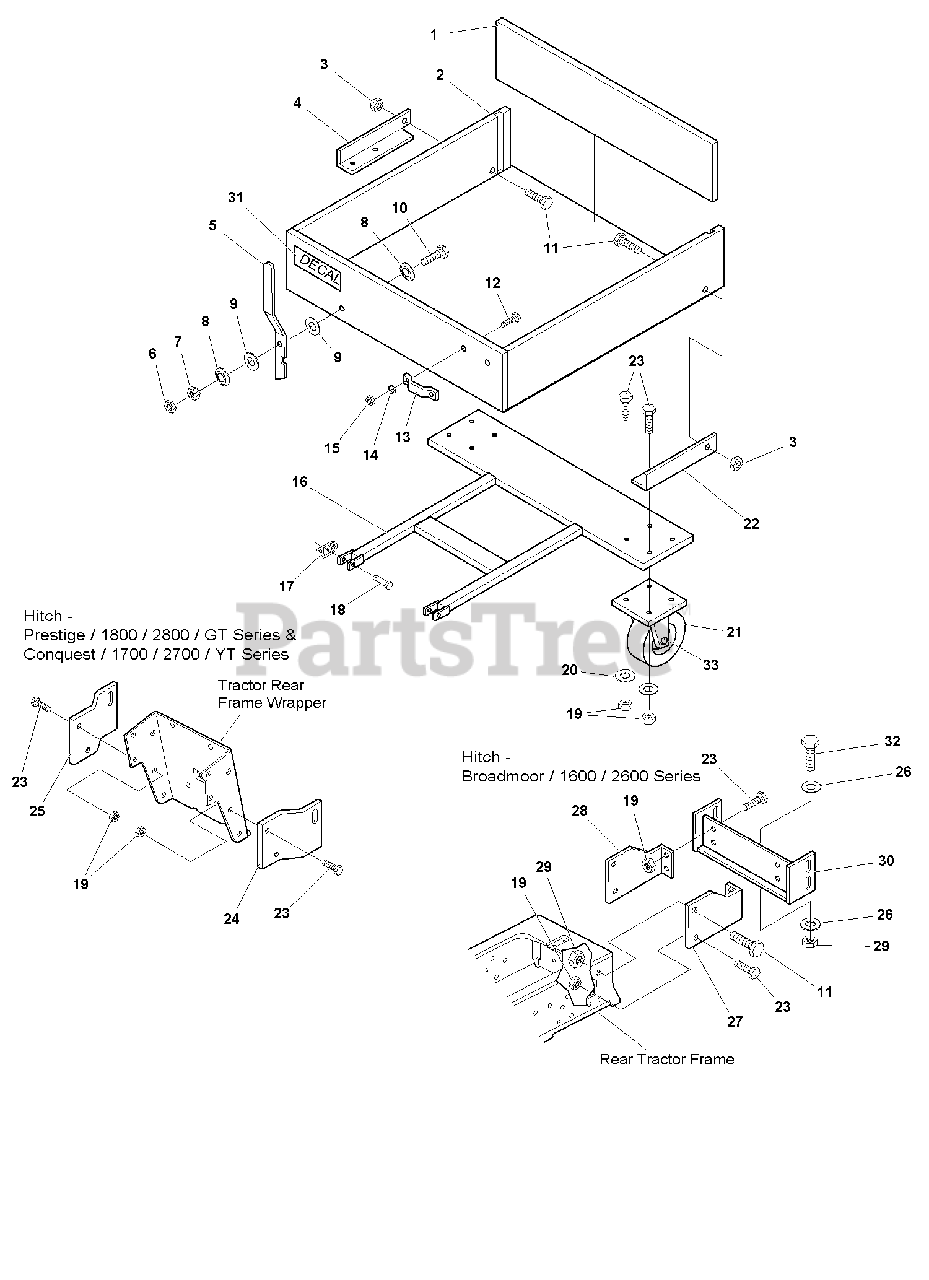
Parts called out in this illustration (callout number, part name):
3	LOCKNUT, Two-Way, 1/2-13
4	BRACKET, Hinge, RH
5	HANDLE, Latch
6	NUT, Jam, 5/16-18
7	NUT, 5/16-18
8	WASHER, Compression, 5/16
9	WASHER, 5/16
10	CAPSCREW, 5/16-18 x 1-1/4
11	CAPSCREW, Hex Head, 1/2-13 x 1
12	CAPSCREW, Hex Head, 1/4-20 x 1/2
13	HANDLE, Lift
14	LOCKWASHER, 1/4
15	NUT, 1/4-20
17	SAFETY CLIP
18	PIN, Round Head, 1/2 x 1-1/2
19	LOCKNUT, Center Lock, 3/8-16
20	WASHER, 3/8
21	WHEEL ASSEMBLY, (Includes Item # 31)
22	BRACKET, Hinge, LH
23	CAPSCREW, 3/8-16 x 1
24	BRACKET, Hitch, LH
25	BRACKET, Hitch, RH
26	WASHER, 1/2
27	ADAPTER, Hitch, LH
28	ADAPTER, Hitch, RH
29	LOCKNUT, Center Lock, 1/2-13
31	DECAL, No Riders, Max. Weight 300 Lbs.
32	CAPSCREW, Hex Head, 1/2-13 x 1-1/4
33	BEARING, Wheel
